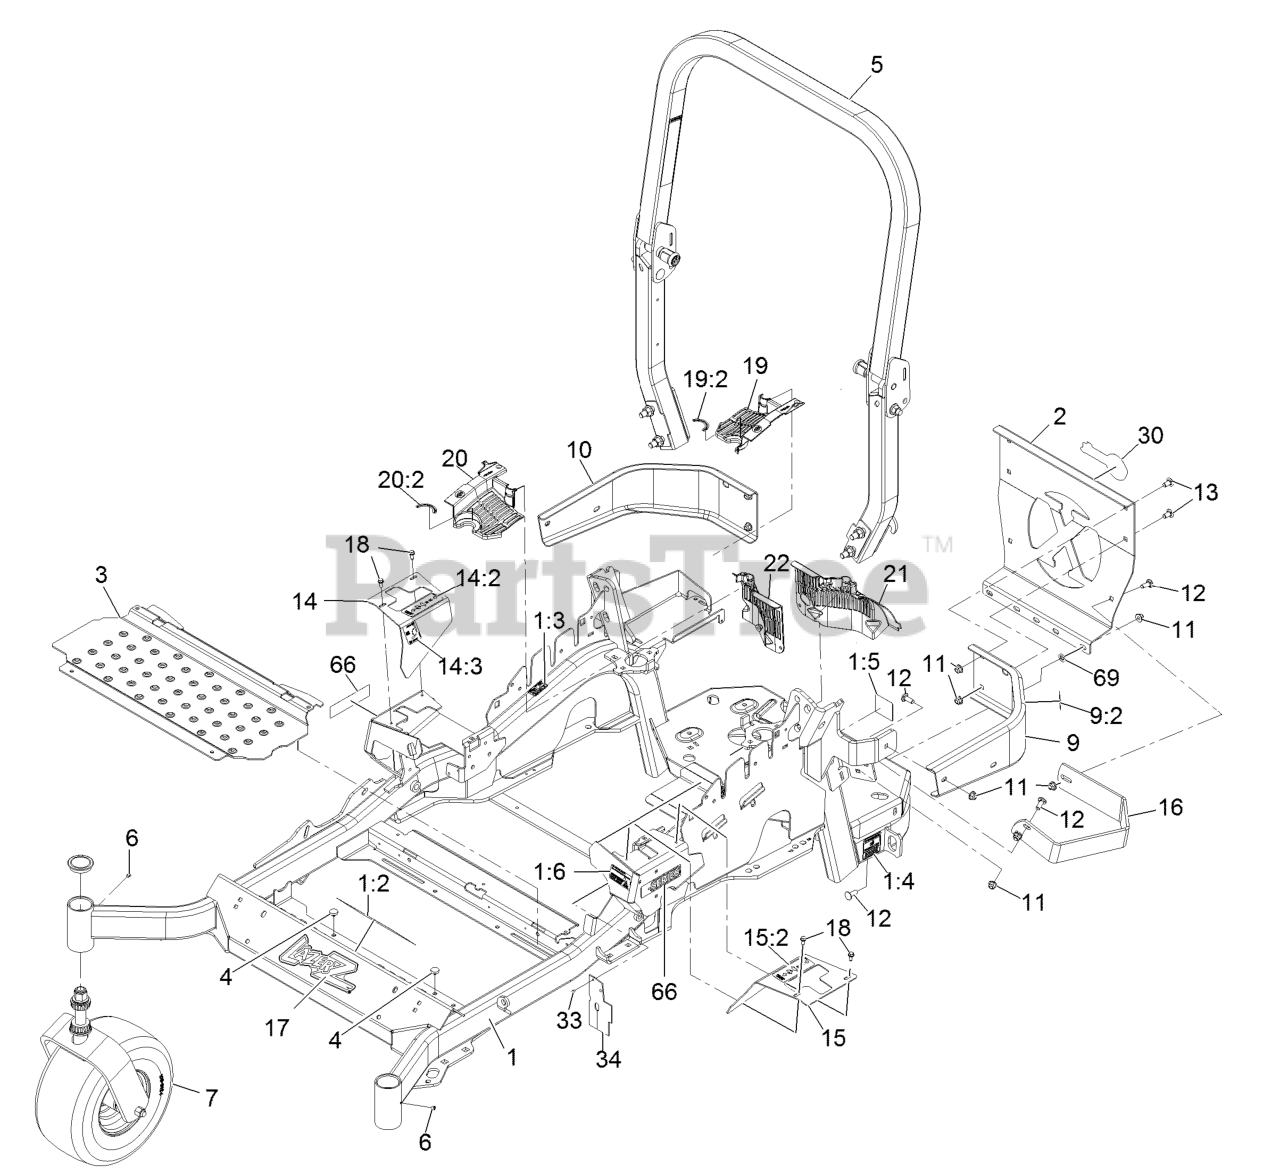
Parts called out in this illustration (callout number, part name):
1	MAINFRAME ASM
1:2	DECAL-SLOPE
1:3	DECAL-CAUTION
1:4	DECAL-BELT DRIVE
1:5	DECAL-SPARK ARRESTER
1:6	DECAL-FUEL FILL
2	PLATE,REAR GUARD
5	ROPS ASM
7	Front Caster W/Fork Asm
9	LH BUMPER ASM
9:2	DECAL-CAUTION
10	BUMPER-RH
11	NUT-HF, NI
12	SCREW-CARR
13	SCREW-CARR
14	RH MOTION CONTROL COVER ASM
14:2	DECAL-MOTION CONTROL
14:3	DECAL-PARK BRAKE
15	LH MOTION CONTROL COVER ASM
15:2	DECAL-MOTION CONTROL
17	DECAL,LAZER MODEL
18	SCREW-HWH
19	LH HYDRO GUARD ASM
19:2	DECAL-HYDRO OIL
20	RH HYDRO GUARD ASM
20:2	DECAL-HYDRO OIL
21	GUARD-HYDRO, REAR (LH)
22	GUARD-HYDRO, REAR (RH)
33	RIVET-POP
34	DEFLECTOR-AIR FLOW
66	DECAL-E-SERIES
69	NUT-PUSH
